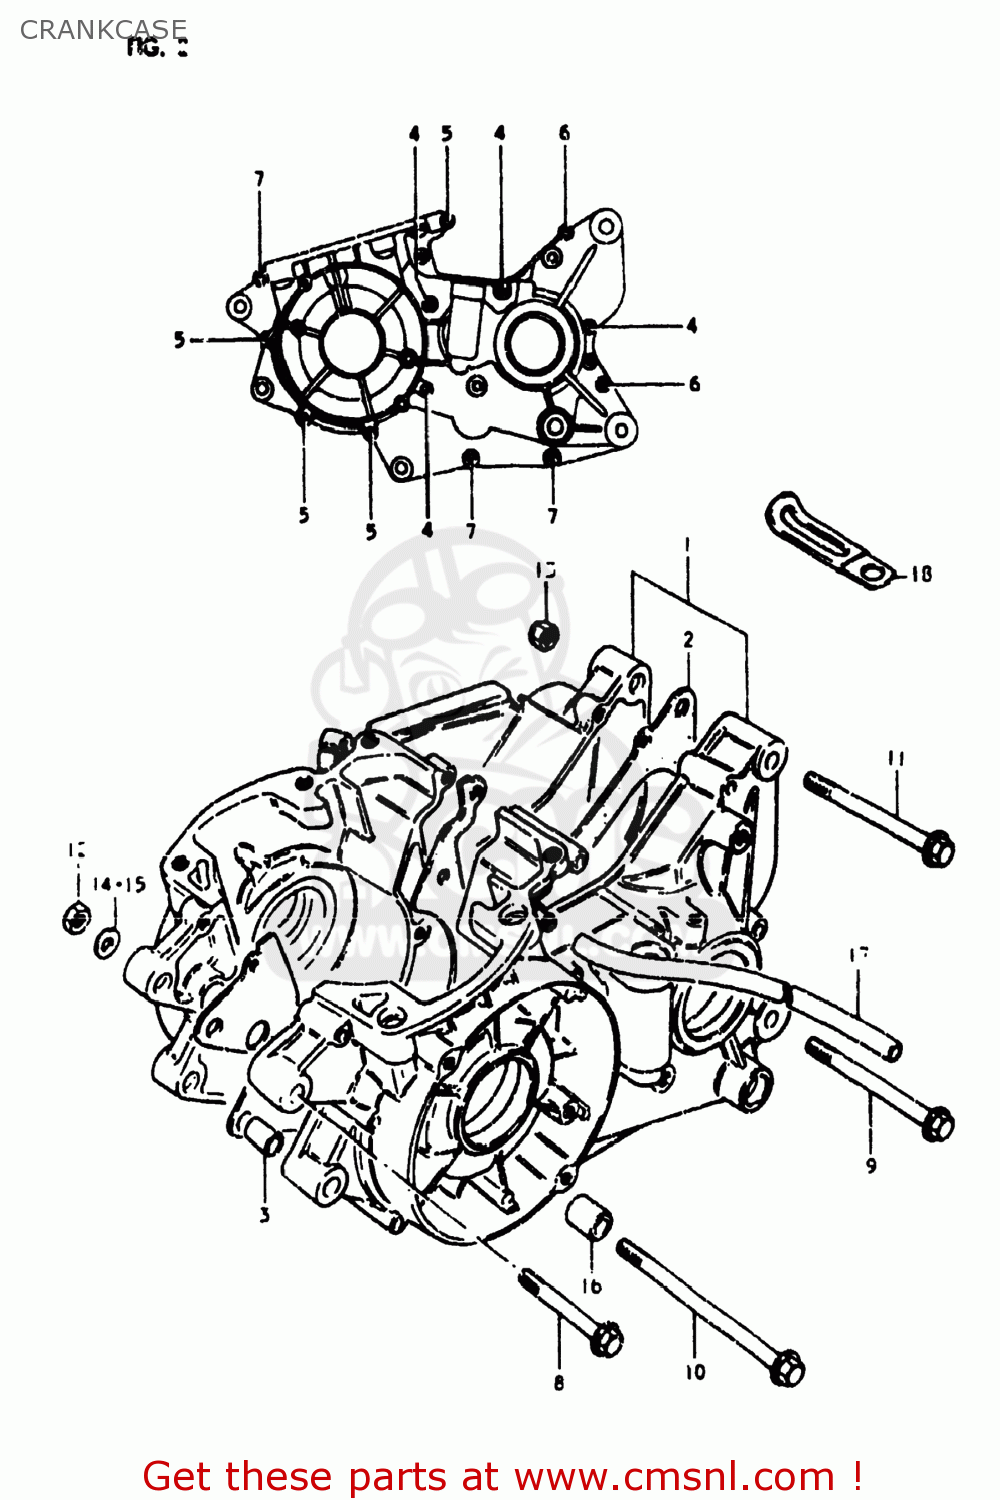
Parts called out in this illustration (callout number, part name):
1	CRANKCASE SET
2	GASKET,CRANKCASE (MCA)
3	PIN
4	SCREW 6X65
5	SCREW
6	SCREW
7	SCREW (6X35)
8	BOLT(8X67)
9	BOLT
10	BOLT
11	BOLT
12	NUT
13	NUT
14	WASHER
15	WASHER
16	SPACER(8.6X16X26)
17	HOSE
18	CLAMP
